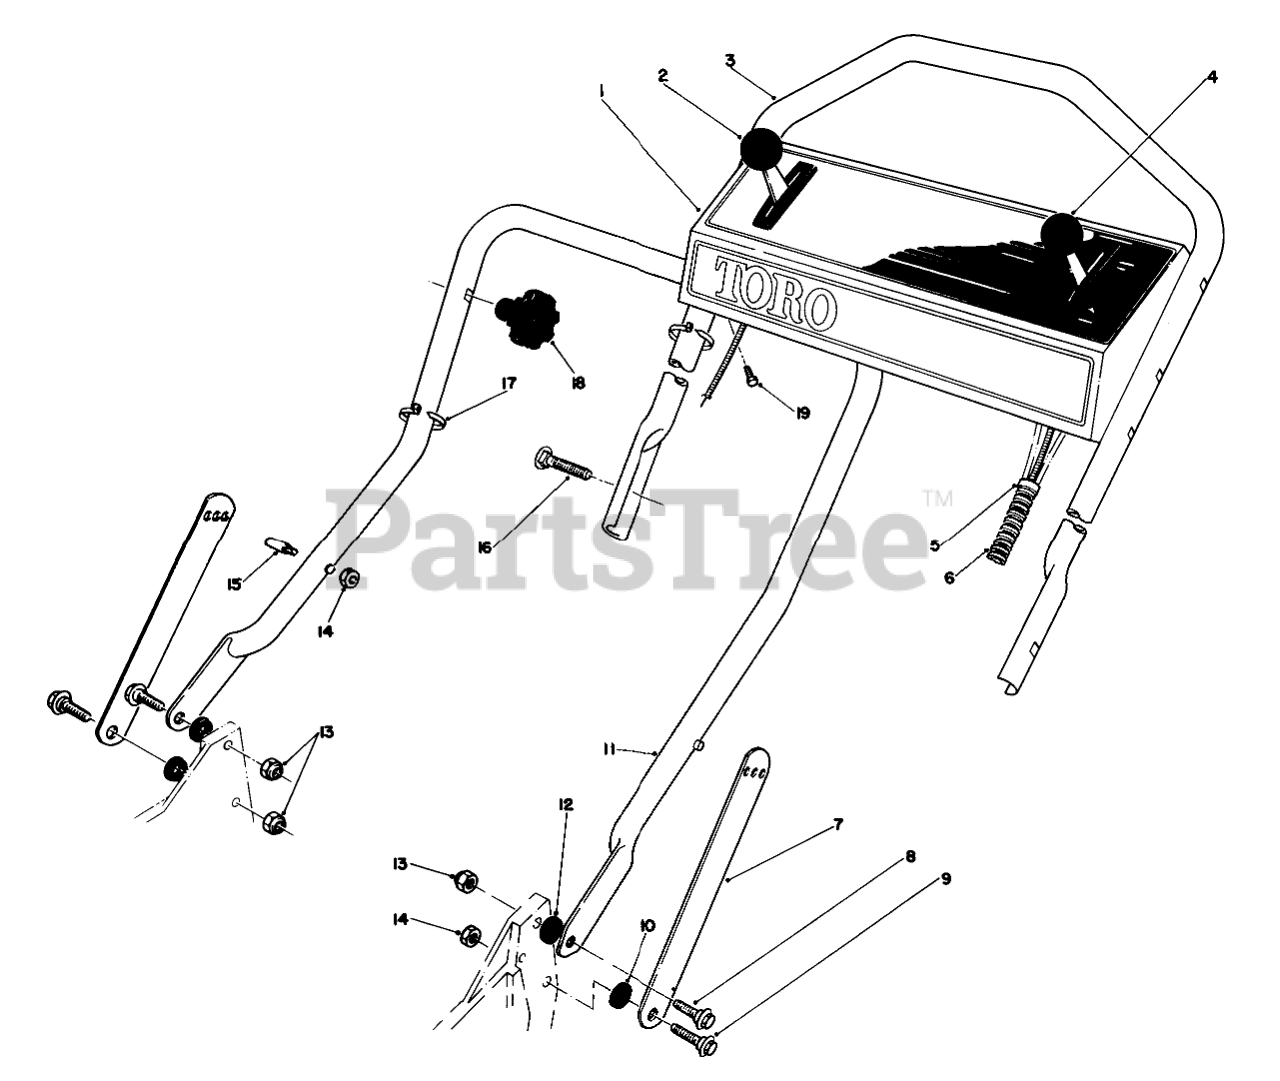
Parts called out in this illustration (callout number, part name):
1	Panel-Control
2	SERVICE THROTTLE CONTRO
3	Handle-Upper
4	THROTTLE CONT-SERVICE
5	FITTING-RING
6	CONTROL CABLE COVER
7	Handle Latch
8	SCREW-SHOULDER
9	SCREW-SHOULDER
10	SPACER
11	LOWER HANDLE ASM
12	SPACER
13	NUT-LOCK, NI
14	NUT-LOCK, NI
15	HANDLE PIN
16	5/16-18 X 2 HNDLE SCREW
17	TIE-CABLE
19	SCREW-HWHTF
